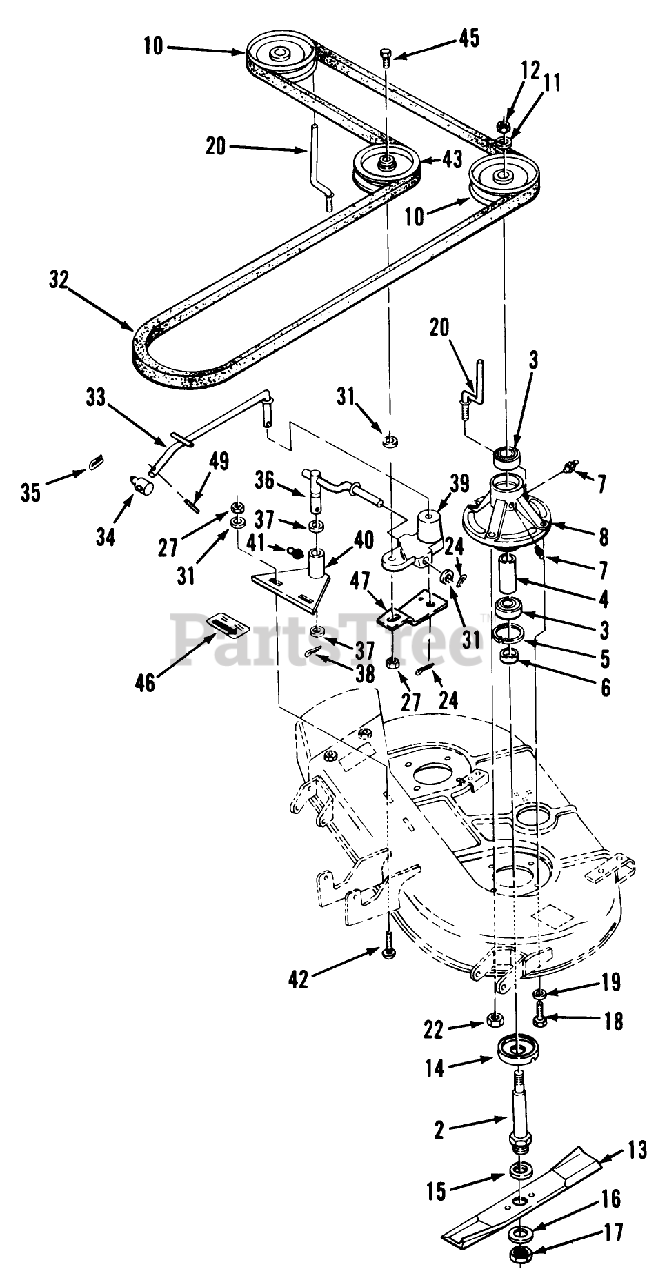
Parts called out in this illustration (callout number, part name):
2	SHAFT SPINDLE
3	BEARING-BALL
5	Ring-Snap
6	SPACER-BLADE
7	Fitting-Grease
8	HOUSING-SPINDLE
10	PULLEY-BLADE
11	Lockwasher
12	Nut
13	BLADE 18.75
14	CUP-SPINDLE
15	Washer
16	Washer
17	Nut
18	BOLT
19	LOCKWASHER
20	ROD-GUIDE
22	NUT
24	Pop Rivet
27	NUT
31	Washer
32	BELT-V
33	ASS'Y-ROD IDLER B
34	TRUNNION-LIFT
35	Hairpin Cotter
36	ARM ASSEMBLY R
37	WASHER
38	Cotter Pin
39	BLOCK IDLER
40	IDLER BRACKET ASS R
41	FITTING-GREASE
42	Bolt
43	PULLEY-FLAT IDLER
45	Bolt
46	DECAL-BELT ADJUST
47	ANCHOR-SPRING B
49	Pin-Roll
